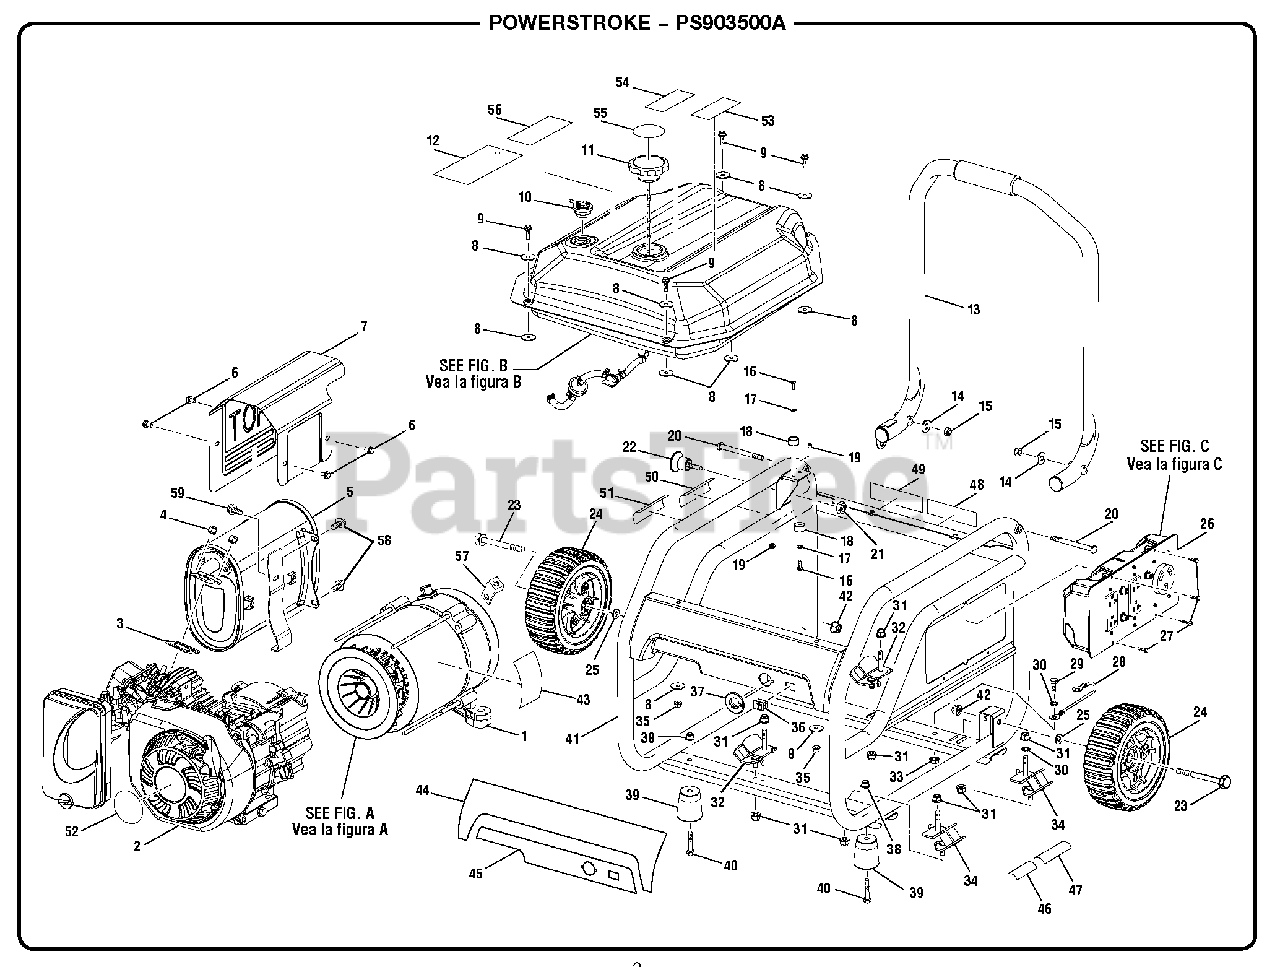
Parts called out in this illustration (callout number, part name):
1	Generator Head Assembly
2	Engine (212 cc)
3	Muffler Gasket
4	Lock Nut (M8)
6	Bolt (M6 x 10 mm)
7	Heat Shield
8	Washer (M8)
9	Bolt (M6 x 1 in., Hex Hd.)
10	Fuel Tank Vapor Vent
11	Fuel Cap Assembly
12	Warning Hangtag
13	Handle Assembly
14	Washer (5/16 in.)
15	Lock Nut (5/16-18, Hex Hd.)
16	Bolt (M4 x 12.5 mm, Hex Hd.)
17	Washer (M4)
18	Rubber Bumper
19	Flange Nut (M4)
20	Pivot Pin (Handle)
21	Hex Nut (1/2-20)
22	Quick Release Pin
23	Axle Bolt (M10 x 110 mm, Hex Hd.)
25	Washer (M10)
26	Control Panel Assembly
27	Screw (6-20 x 3/8 in., Type B)
28	Ground Wire Assembly
29	Bolt (5/16-18 x 3/4 in.)
30	Star Washer (5/16 in.)
31	Lock Nut (M8)
32	Isolator (Left)
33	Hex Nut (5/16-18)
34	Isolator (Right)
35	Flange Nut (M6)
36	Stop Switch
37	Fuel Valve Bezel
38	Lock Nut (M8)
40	Bolt (M8 x 45 mm, Flange Hex Hd.)
41	Carrier Assembly
42	Lock Nut (M10)
43	Data Label
44	Logo Label
45	Start Label
46	Inquires Label
47	Lubricant Label
48	Ground Warning Label
49	Fire Danger Label
50	Hot Surface Label
51	Combustion Label
52	Recoil Label
53	CPSC Label
54	E-85 Label
55	Fuel Stabilizer Label
56	Danger Label
57	Ground Lug
58	Bolt (M8 x 1.25 in., Flange Hex Hd.)
59	Bolt (M6 x 14 mm, Flange Hex Hd.)
60	Muffler Bracket
